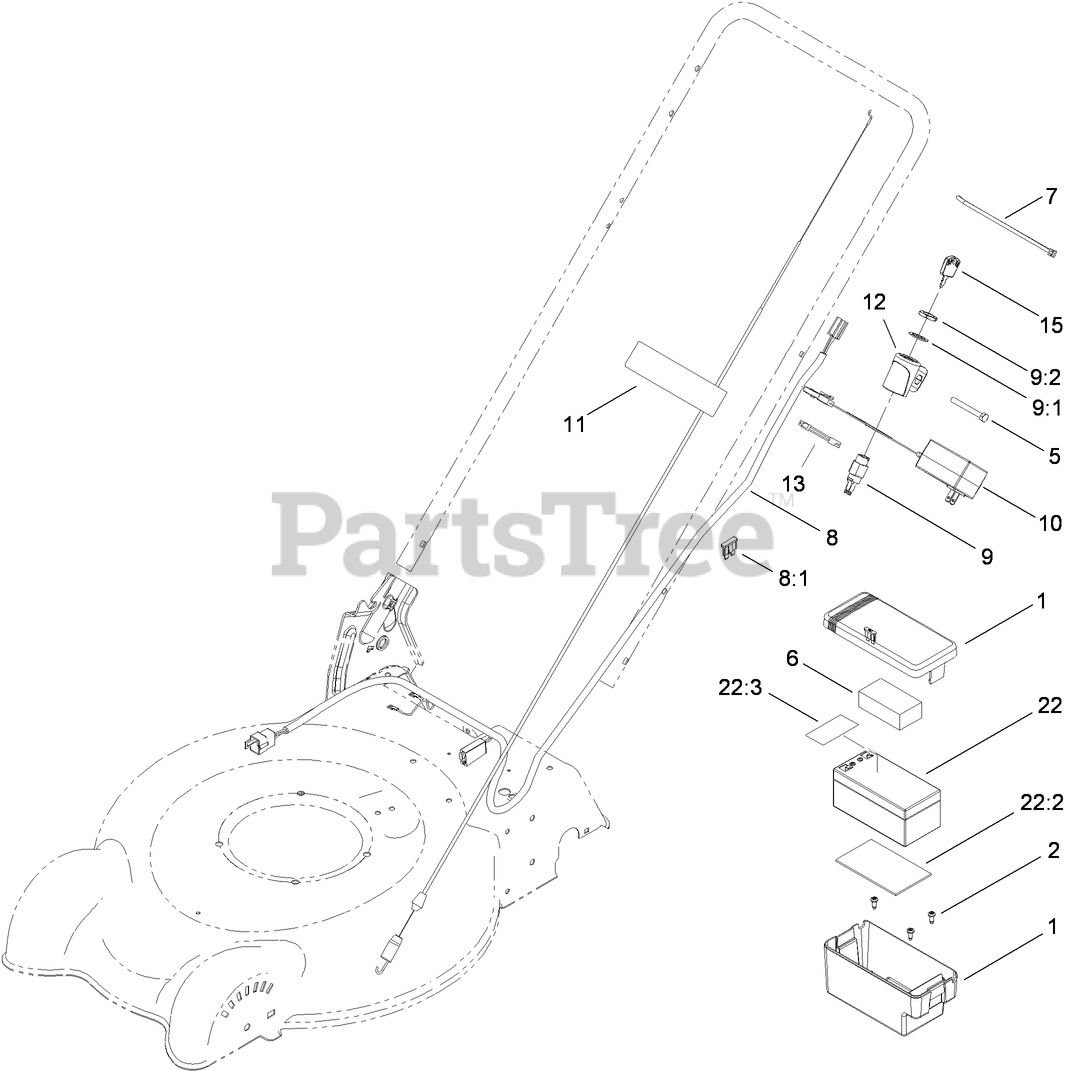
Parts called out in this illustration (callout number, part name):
1	BATTERY BOX ASM
2	SCREW-FORMING, THREAD
5	SCREW-HH
6	FOAM-BATTERY, TOP
7	TIE-CABLE
8	HARNESS-WIRE
8:1	FUSE-40 AMP
9	STARTER SWITCH ASM
9:1	WASHER-LOCK
9:2	NUT-HH
10	CHARGER-EUROPEAN, 12V DC
11	DECAL-WARNING
12	MOUNT-SWITCH
13	ADAPTER-CHARGER
22	BATTERY-WET
22:2	FOAM-BATTERY
22:3	DECAL-TERMINAL, BATTERY
